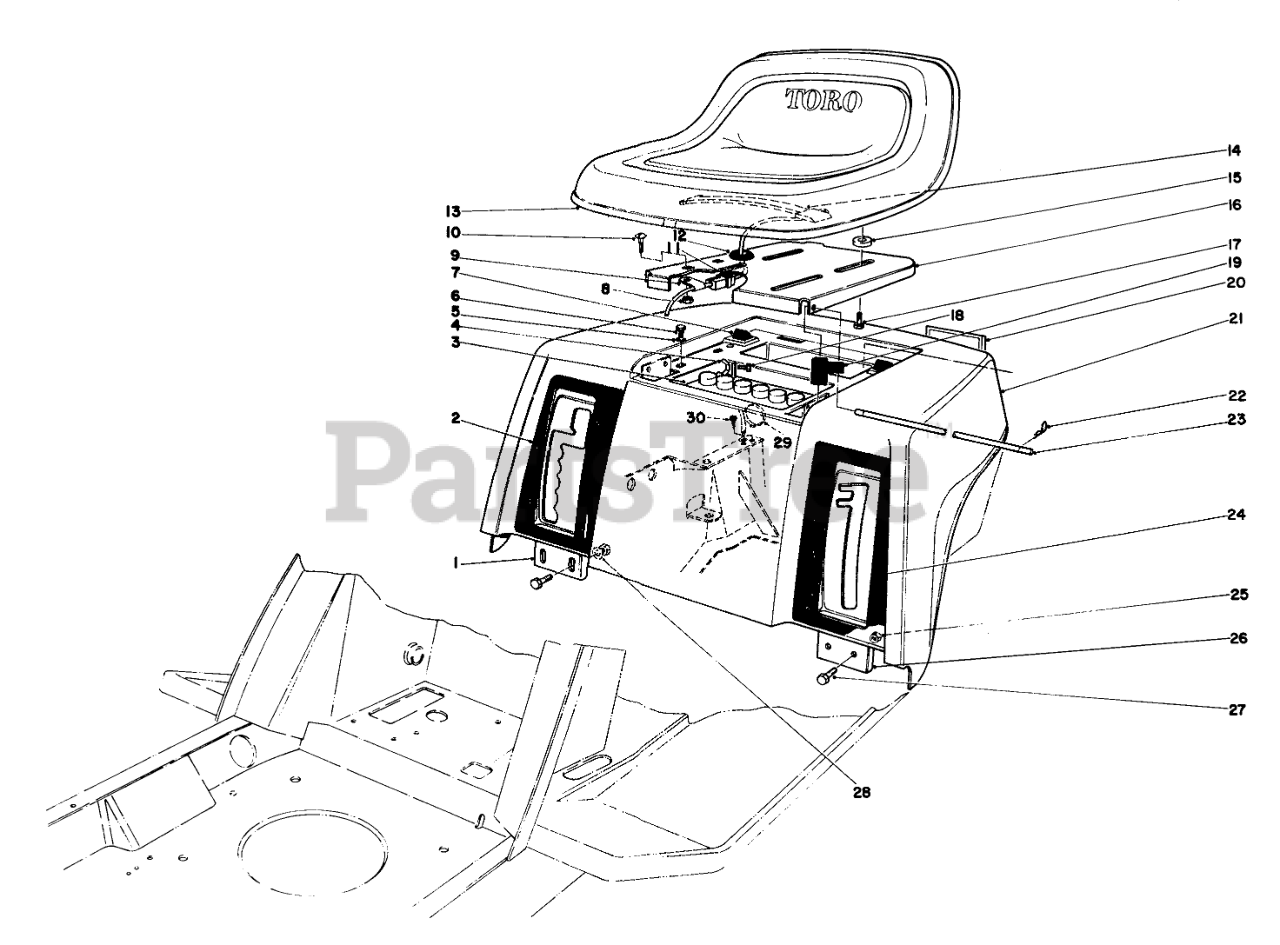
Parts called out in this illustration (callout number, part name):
1	DETENT PLATE B
2	Decal Transmission
3	Battery
4	NUT-WING
5	WASHER
6	SCREW-HWHTF
7	SEAT BUMPER
8	NUT-KEPS
9	CLAMP
10	SCREW-CARR
11	Female Connector
12	GROMMET
14	SWITCH-SEAT
15	SPACER-PIN, MOUNTING
16	SEAT SUPPORT R
17	SCREW-HHF
18	SCREW-HH
19	BOOT-TERMINAL
20	REFLECTOR
21	Rear Body (Incl. Ref. #2 & 24)
22	PIN-COTTER
23	PIVOT-SEAT
24	Decal Height of Cut
25	NUT-LOCK, NI
26	Quadrant Height of Cut
27	SCREW-HH
28	WASHER-PLAIN
29	TIE-CABLE
30	SCREW-HWHTF
